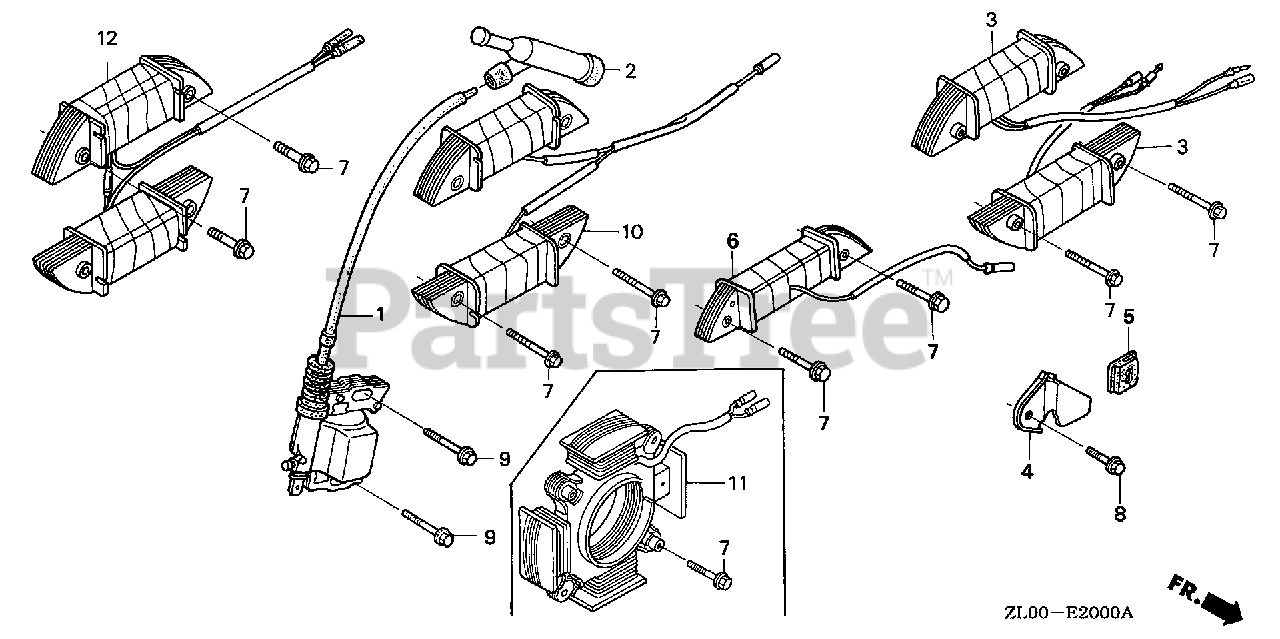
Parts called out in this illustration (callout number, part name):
1	COIL ASSY., IGNITION
2	CAP ASSY., NOISE SUPPRESSOR (NICHIWA Y-EZ RTFM256)
4	CLAMP, WIRE
5	GROMMET, WIRE
7	BOLT, FLANGE (6X28) (CT200)
8	BOLT, FLANGE (5X10)
9	BOLT, FLANGE (6X25) (CT200)
11	COIL ASSY., CHARGE (12V-7A)
